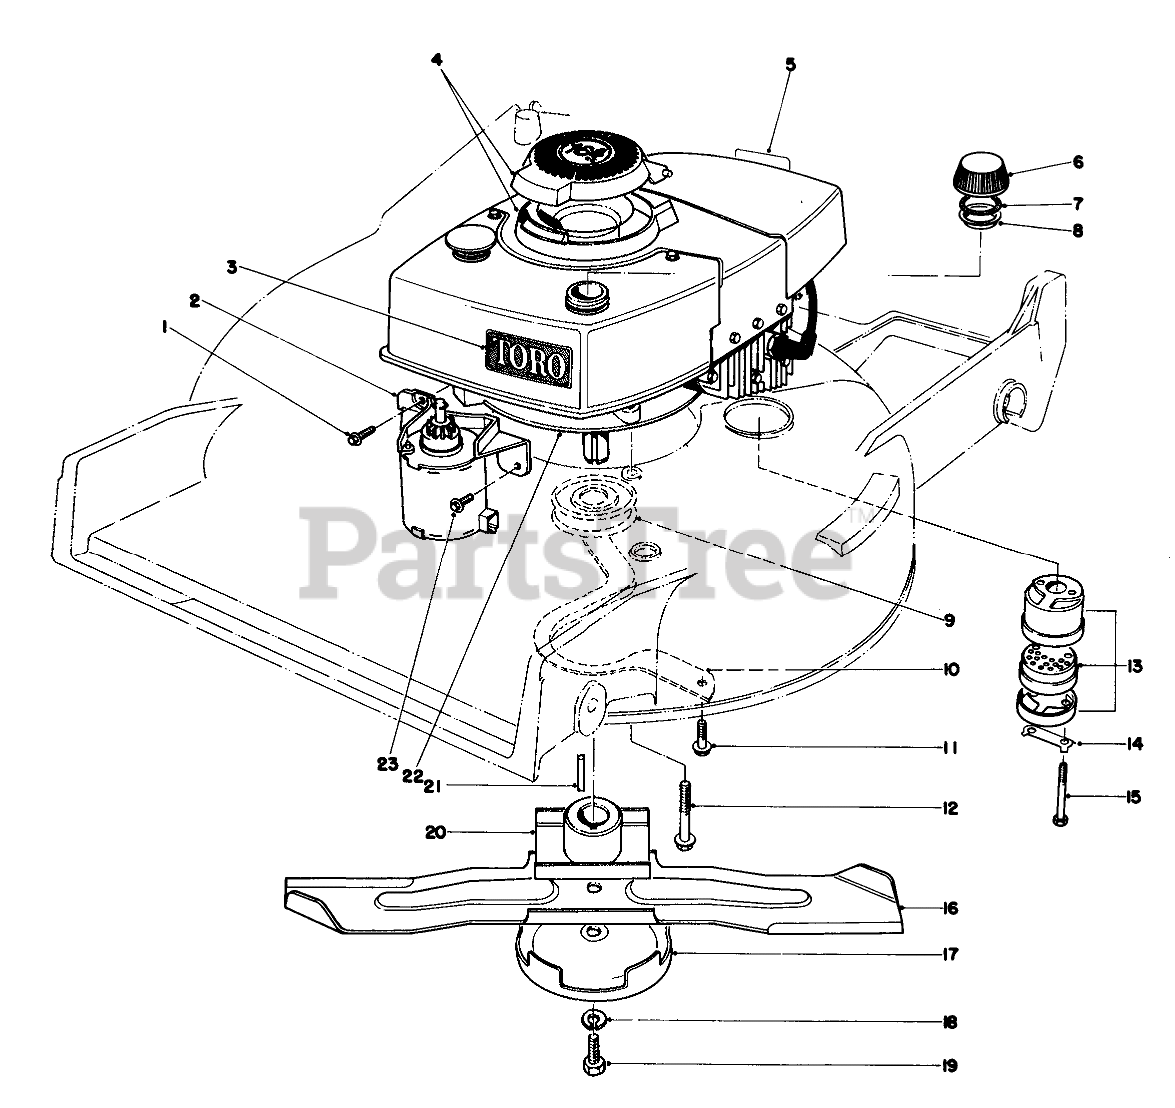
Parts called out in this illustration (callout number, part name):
1	Screw
2	Starter Motor
3	Decal Tow
4	COVER ASM
5	Decal-Maintenan
6	Gas Cap (Incl. Ref. #7 & 8)
7	GASKET
8	GAS CAP BAFFLE
9	DRIVER PULLEY
10	BELT GUIDE
11	Screw
12	SCREW-HWHTF
13	Muffler Assembly (Incl. Ref. 14 & 15)
14	CLIP - LOCKING
15	SCREW-HH
16	Blade
17	AntiScalp Cup
18	WASHER-LOCK
19	BLADE SCREW
20	BLADE RETAINER WA(BLACK)
21	KEY-SQUARE
22	Engine
23	SCREW
